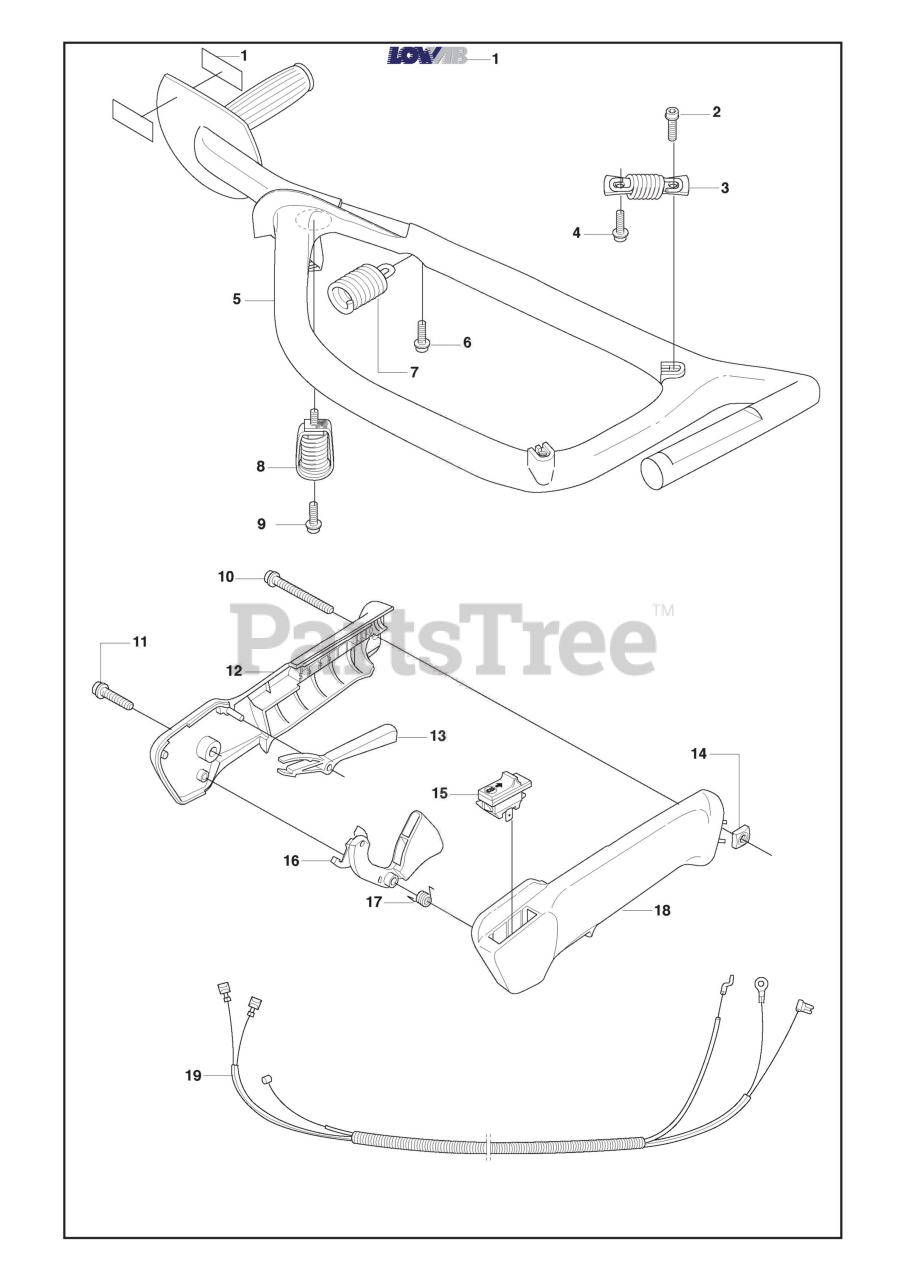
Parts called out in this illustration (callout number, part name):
7	VIBRATION ABSORBER
8	SCREW
9	SCREW
10	SCREW
12	THROTTLE CATCH
14	REAR SPRING
15	STOP BUTTON
16	THROTTLE CONTROL
19	WIRING ASSY HS
